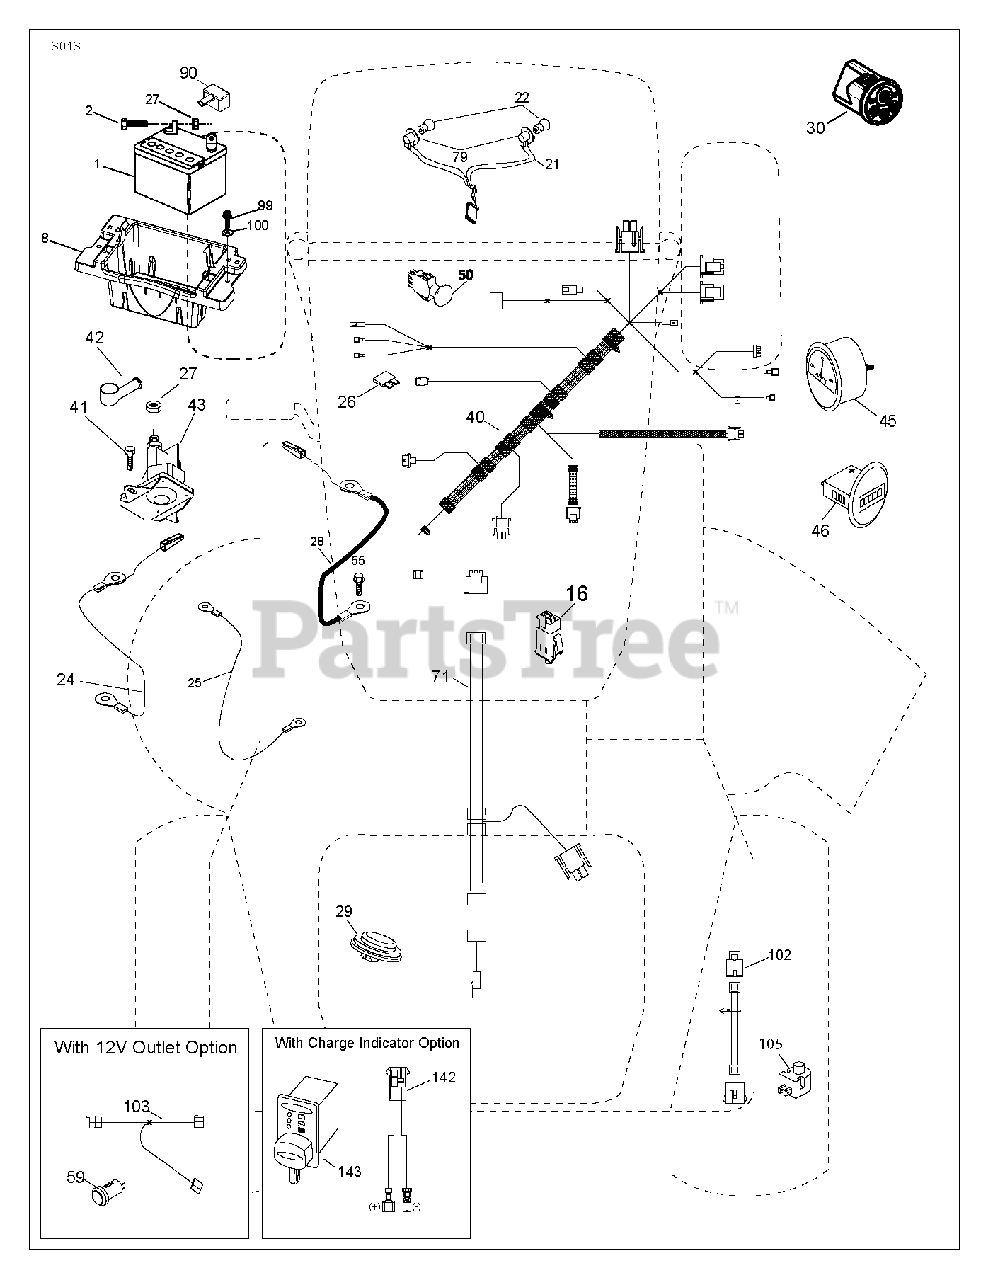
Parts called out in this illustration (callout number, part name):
1	Battery, Dry 30 Amp
2	BOLT.HEX.1/4.X.3/4.DICHROMATE
8	TRAY.BATTERY BOX.FRONT
16	SWITCH INTERLOOK PUSH-IN
21	HARNESS.LIGHT W/4152J BULBS
24	CABLE.BTRY.HARN.POS.LEAD
25	CABLE.STARTER.8GA.17.5
26	FUSE 20AMP
27	NUT
28	CABLE.GROUND.STARTER
29	SWITCH.SEAT.OPC.GRY.BUTTON/CAP
30	SWITCH.ASM.SMARTSWITCH.MY15.TR
40	HARNESS.DASH.EL.SIS.RND.MY15
41	SCREW
42	TERMINAL COVER
43	SOLENOID.W/BRASS.PLUNGER
45	GAUGE.AMMETER.SILVER/WHITE
46	GAUGE.HOUR.METER.SILVER/WHITE
50	RB PTO.SWITCH.8 TERMINAL.BLACK
55	SCREW 5/16"
71	HARNESS.CHAS.TEX.SIS.FBAT.TWIN
79	BULB HOLDER ASM.
90	COVER.TERMINAL.BATTERY
99	SCREW HEXWSHR 1/4-20X3/4
100	WASHER
102	HARNESS PIGTAIL PCH TEX ROS
105	REVERSE SWITCH
142	CHARGE.PORT.PIGTAIL HARNESS
143	CHARGE.PORT
